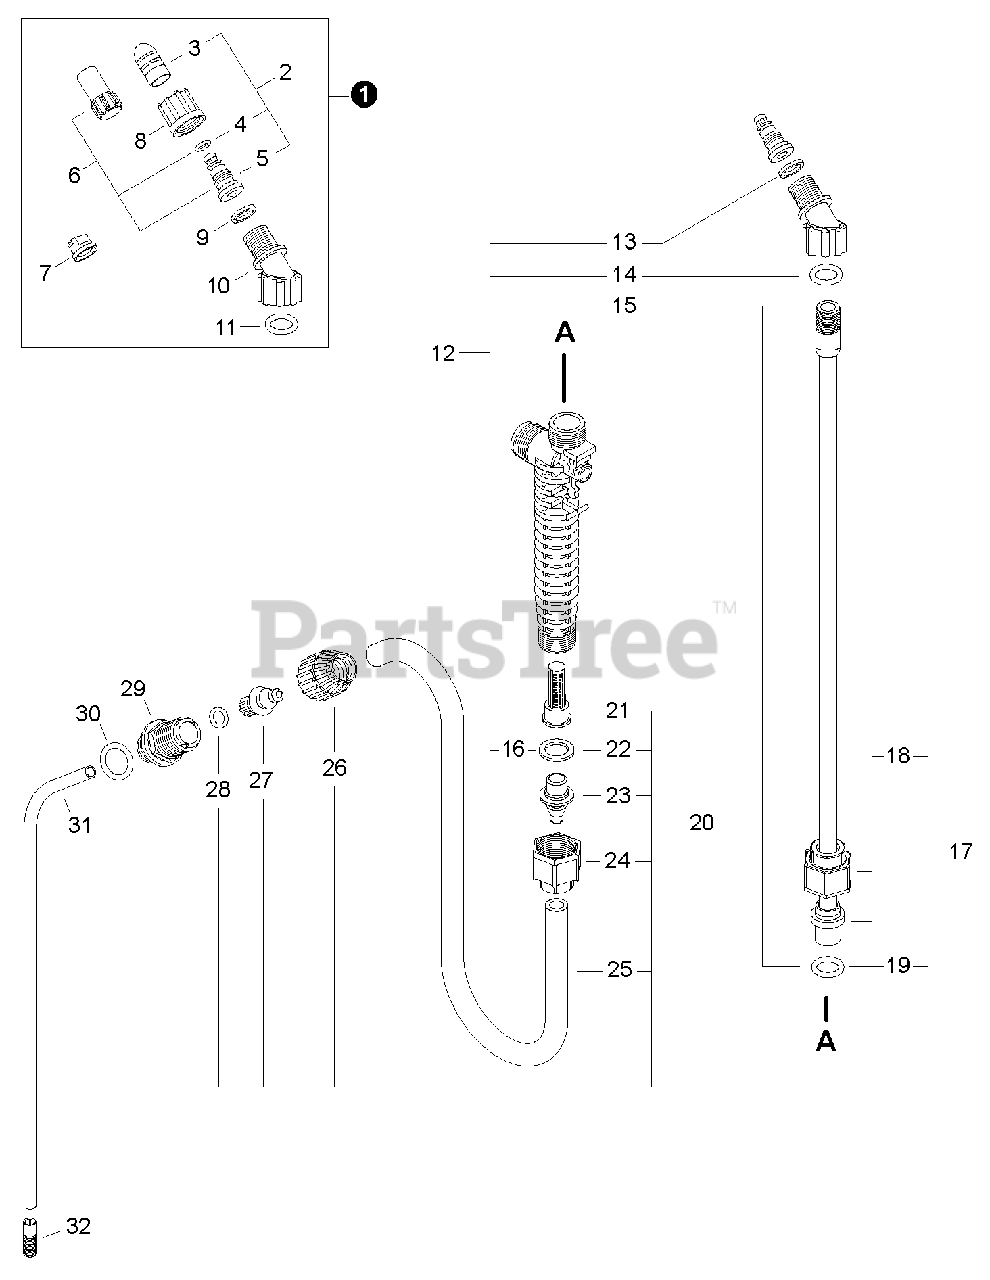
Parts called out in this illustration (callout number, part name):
1	NOZZLE KIT
2	NOZZLE KIT - BRASS
3	CAP, NOZZLE - BRASS
4	O-RING, NOZZLE
5	BODY, NOZZLE
6	NOZZLE KIT - PLASTIC
7	NOZZLE - FLAT FAN
8	NUT, NOZZLE
9	GASKET, NOZZLE
10	ELBOW, NOZZLE
11	O-RING, ELBOW
12	WAND GASKET KIT
13	GASKET, NOZZLE
14	O-RING, ELBOW
16	GASKET, ADAPTER
17	SPRAY WAND ASSY
18	WAND, SPRAYER
20	HOSE KIT
21	FILTER, SPRAY GUN
22	GASKET, ADAPTER
23	ADAPTER, HOSE - BLACK
24	NUT, HOSE
25	HOSE - 1210mm -- CLEAR
26	NUT, TANK
27	ADAPTER, HOSE - WHITE
28	O-RING, ADAPTER
29	OUTLET, TANK - 15/16
30	O-RING, TANK OUTLET
31	TUBE, OUTLET 22-3/8"
32	FILTER, OUTLET
